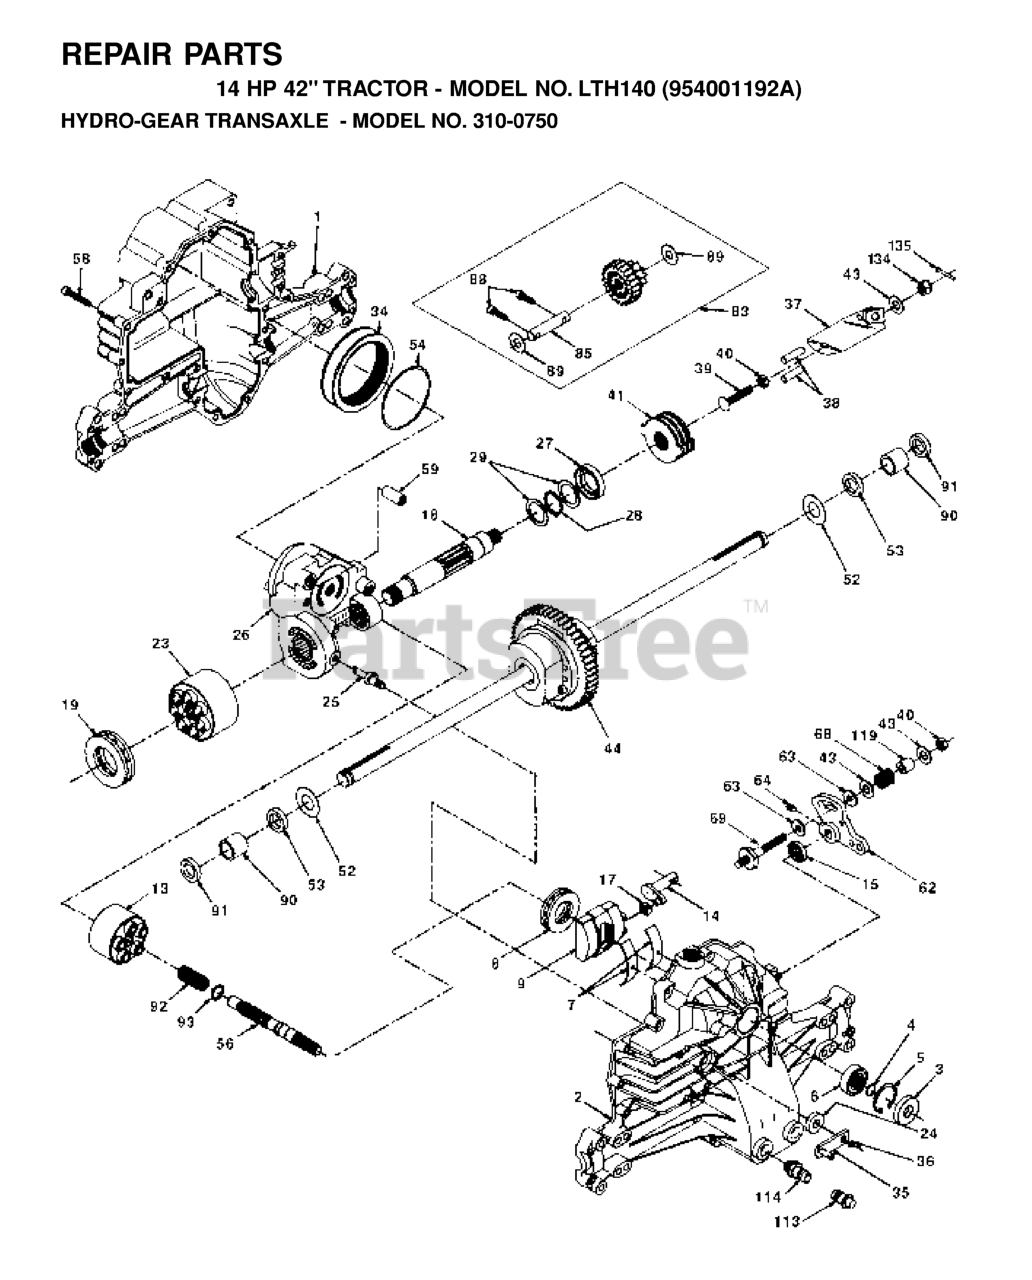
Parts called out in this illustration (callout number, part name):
1	LOWER HOUSING
2	HOUSING UPPER 70255
3	SEAL.LIP.H-G.(9008000-0128)
4	RING RETAINING 2003016
5	RING.RETAINING.(2003052)
6	BALL BEARING
7	CRADLE BEARING
8	THRUST BEARING
9	SWASHPLATE (2003087)
13	BLOCK, CYL ASSY
14	TRUNNION ARM
17	SLOT GUIDE
18	MOTOR SHAFT
19	THRUST BEARING
23	BLOCK, CYL ASSY
25	BYPASS ACTUATOR
26	CENTER SECTION ASSY KIT
28	RETAINING RING
34	ELEMENT, OIL FILTER
35	BYPASS ARM
36	RETAINING RING 44870
37	ACTUATING ARM
38	ACTUATING PIN 44891
40	NUT.LOCK.HX.(H-G PART 50108)
41	BRAKE ROTOR 70135 HYDRO-GEAR
43	WASHER .34X.88X.06.44130
44	KIT SVC DIFF 70130
52	WASHER.HYDRO GEAR.50152
53	SEAL.HYDRO.53901
56	SHAFT.INPUT.50005
58	BOLT #44876
62	CONTROL ARM 50254
63	DAMPENER PUCK
64	SCREW.SET.50018
68	SPRING HELICAL COMP 50277
69	STUD 5/16-24 50284
83	JACK SHAFT ASSY
85	JACK SHAFT
89	WASHER 50132
90	SLEEVE.BEARING 50118
91	RP SEAL, WIPER
92	SPRING 2003014
113	CAP, VENT ASSY
114	O-RING KIT 70110
119	SPACER.HYDRO GEAR 50278
134	NUT.CAS.HYD.44142
135	ID DOT HYDD
